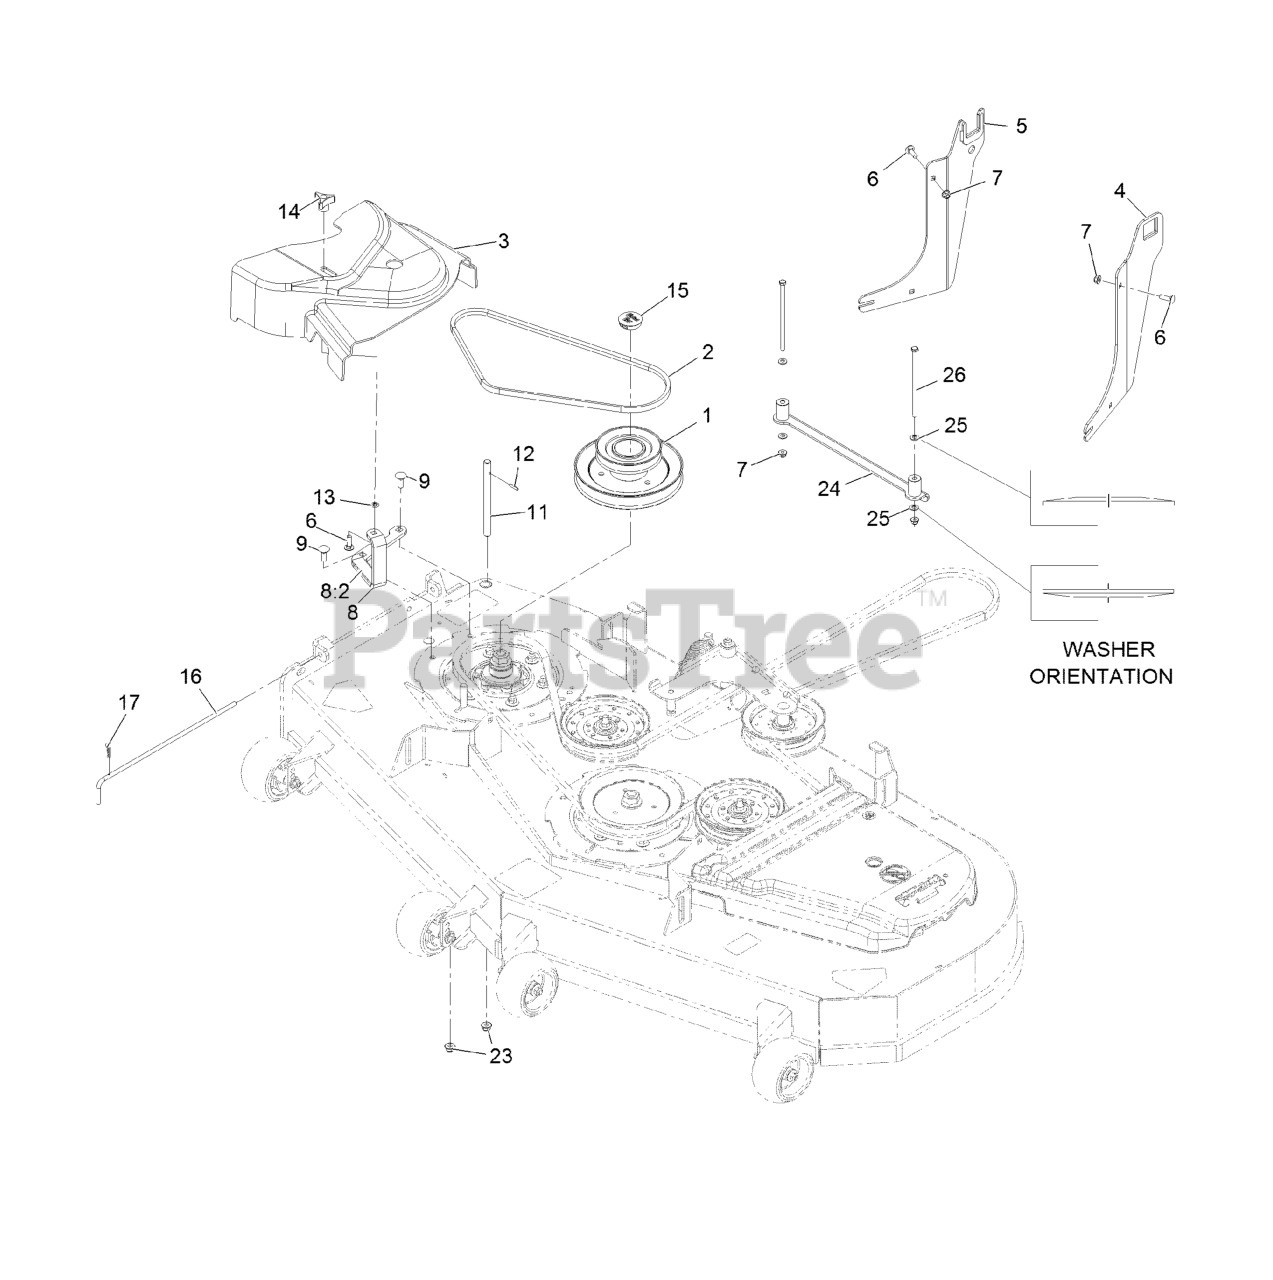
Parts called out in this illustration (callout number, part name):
1	JACKSHAFT,UV DRIVE 604 SPLINED
2	BELT,A 42.32
3	COVER-BELT UVE 60
4	BRACKET ASM, LH
5	BRACKET ASM, RH
6	BOLT-CARR
7	NUT-HF, NI
8	ASM-CVR BRKT W/DECAL
8:2	DECAL-COVER, MISSING
9	BOLT-CARR
11	SHAFT-CATCHER, GRASS
12	PIN-ROLL
13	RING-RETAINING, BOLT
14	KNOB-3 PRONG
15	PLUG, BLACK NYLON 1.75
16	PIN,CHUTE PIVOT
17	PIN-COTTER
23	Nut-Nyloc 3/8-16 Flg
24	ASM-HYDRO GUSSET
25	WASHER-SPRING
26	SCREW HH
